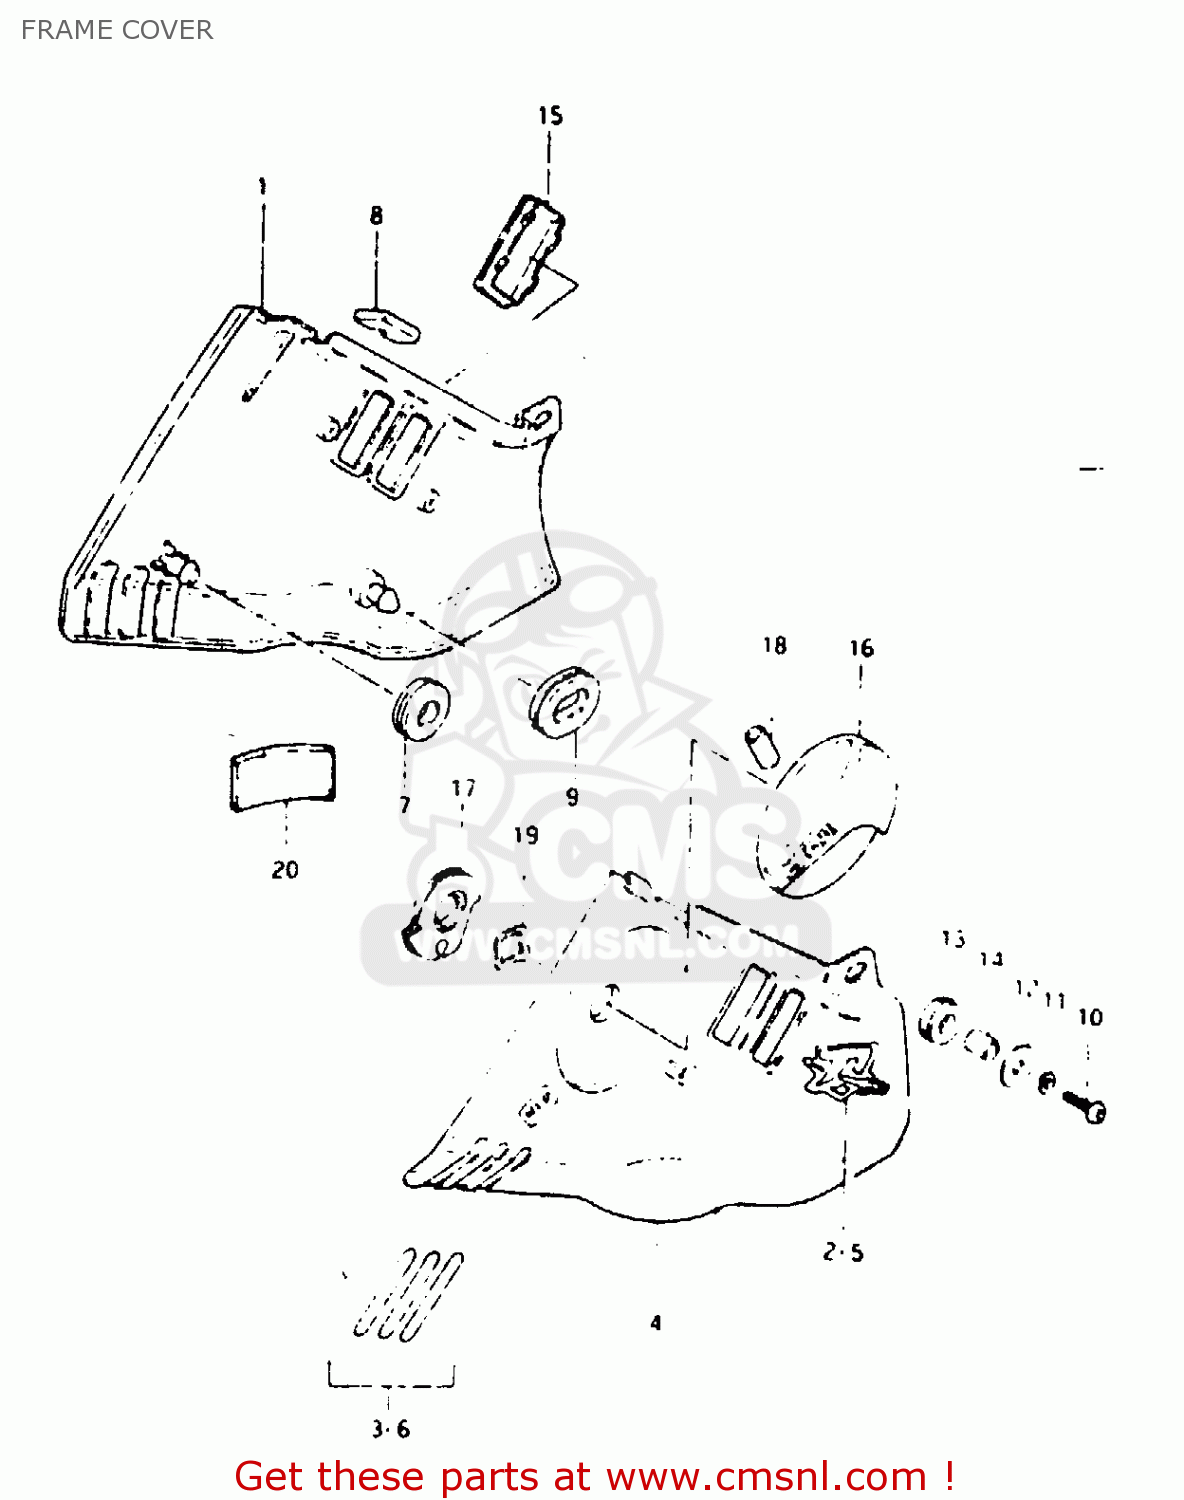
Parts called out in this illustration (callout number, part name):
1	COVER, FRAME RH (SILVER)
2	EMBLEM
3	LABEL,FRAME COVER DENT
4	COVER, FRAME LH (SILVER)
5	EMBLEM
6	LABEL,FRAME COVER
7	CUSHION
8	CUSHION
9	CUSHION
10	SCREW
11	LOCK WASHER
12	WASHER
13	CUSHION
14	SPACER(6.1X9X7.5)
15	CAP,FRAME COVER SWITCH HOLE
16	LEVER,CHOKE CABLE
17	HOLDER, STARTER
18	TUBE,CHOKE CABLE LEVER
19	WASHER
20	PAD
